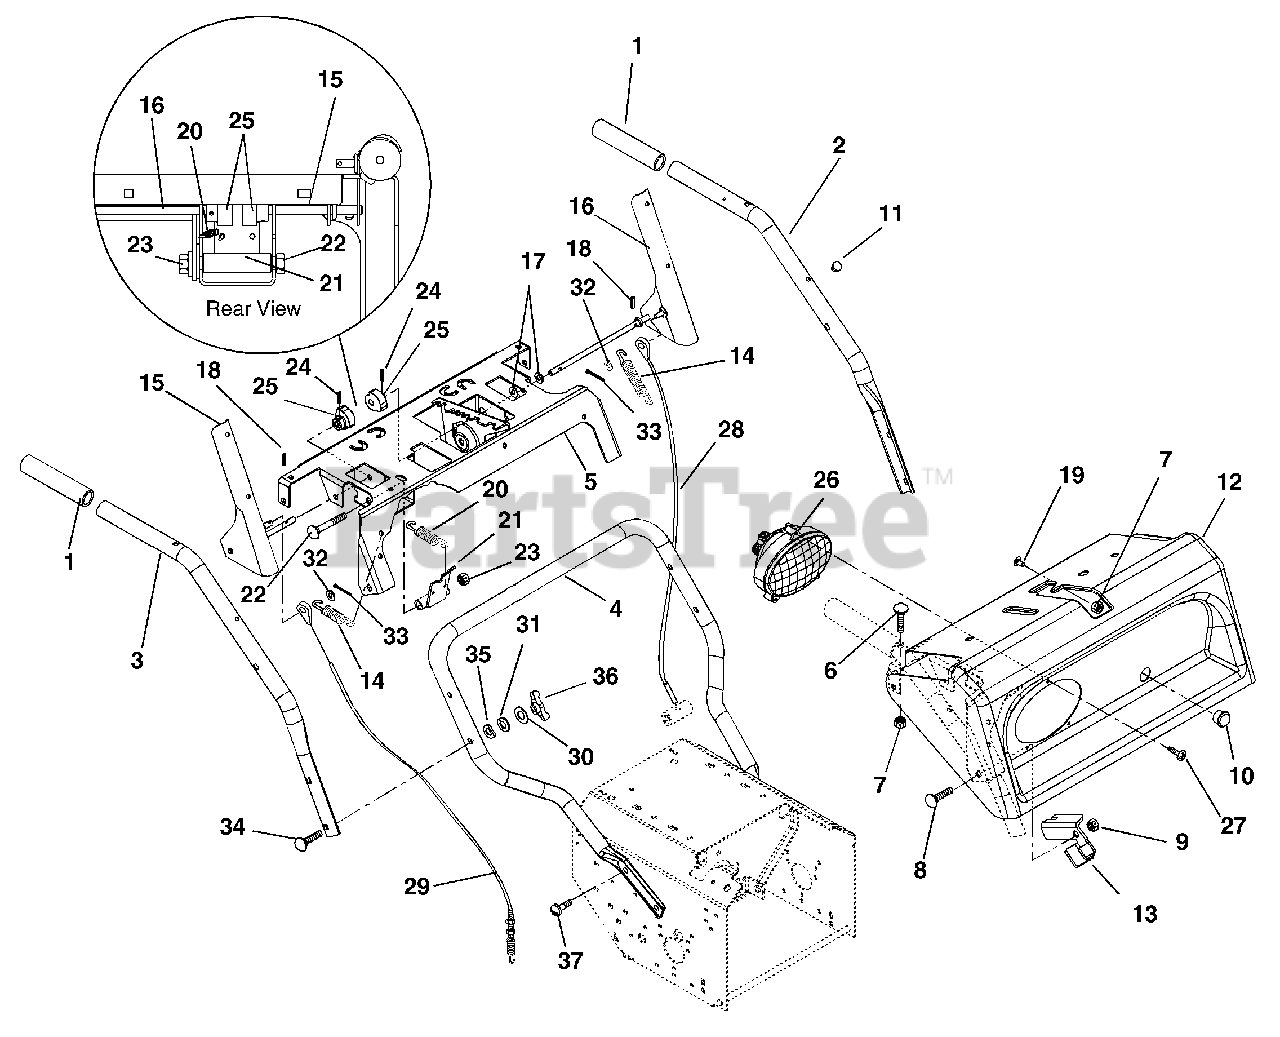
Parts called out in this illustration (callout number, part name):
1	HANDLE GRIP
2	HANDLEBAR, UPPER-RH
3	HANDLEBAR, UPPER-LH
4	HANDLEBAR, LOWER
5	PANEL, SUB
6	BLT-RDHDXLSQNK.25-20X1.25 G5ZC
7	@NUT-LK-CTR .25-20 YWZC
8	@BLT-RDHDSQNK .31-18X1.75 G5YZ
9	@NUT-LK-CTR .31-18 YWZC
10	SNAP BUSHING
12	PANEL W/DECAL - 824
12	PANEL W/DECAL - 724
13	BRACKET, CABLE ANCHOR
14	SPRING-EXT .056X.50X3.76
15	LEVER, RH-COATED
16	LEVER, LH-COATED
17	@WSHR-FL-STL.344X.688X.065YWZC
18	PIN-ROLL .125X.75
19	BLT-RDHDSQSHNK.25-20X.50 YWZC
20	SPRING-EXT .047X.438X1.45
21	ARM, INTERLOCK
22	@BLT-HEX .38-16X3.00 GR5 YWZC
23	@NUT-LK-CTR .38-16 YWZC
24	PIN-ROLL .125X.75
25	CAM, INTERLOCK
26	HEADLAMP, OVAL W/ 1156 BULB
27	SCR-TAP 10-16X.75 HI-LO PPH
28	CABLE, TRACTION
29	CABLE, AUGER
30	WSHR-FL-STL .328X.875X.062YWZC
31	WSHR-LK .312X.097 HVY YWZC
32	@WSHR-FL-STL.281X.62X.065 YWZC
33	@PIN-CTR .09X.50 EXTPRSQCT YWZ
34	@BLT-RDHDSQNK .31-18X2.25 G5YZ
35	WASHER,SADDLE-.320 X.937 X.062
36	KNOB - WING .312-18 UNC
37	BLT SERHFWH .31-18X.62 GR5YWZC
